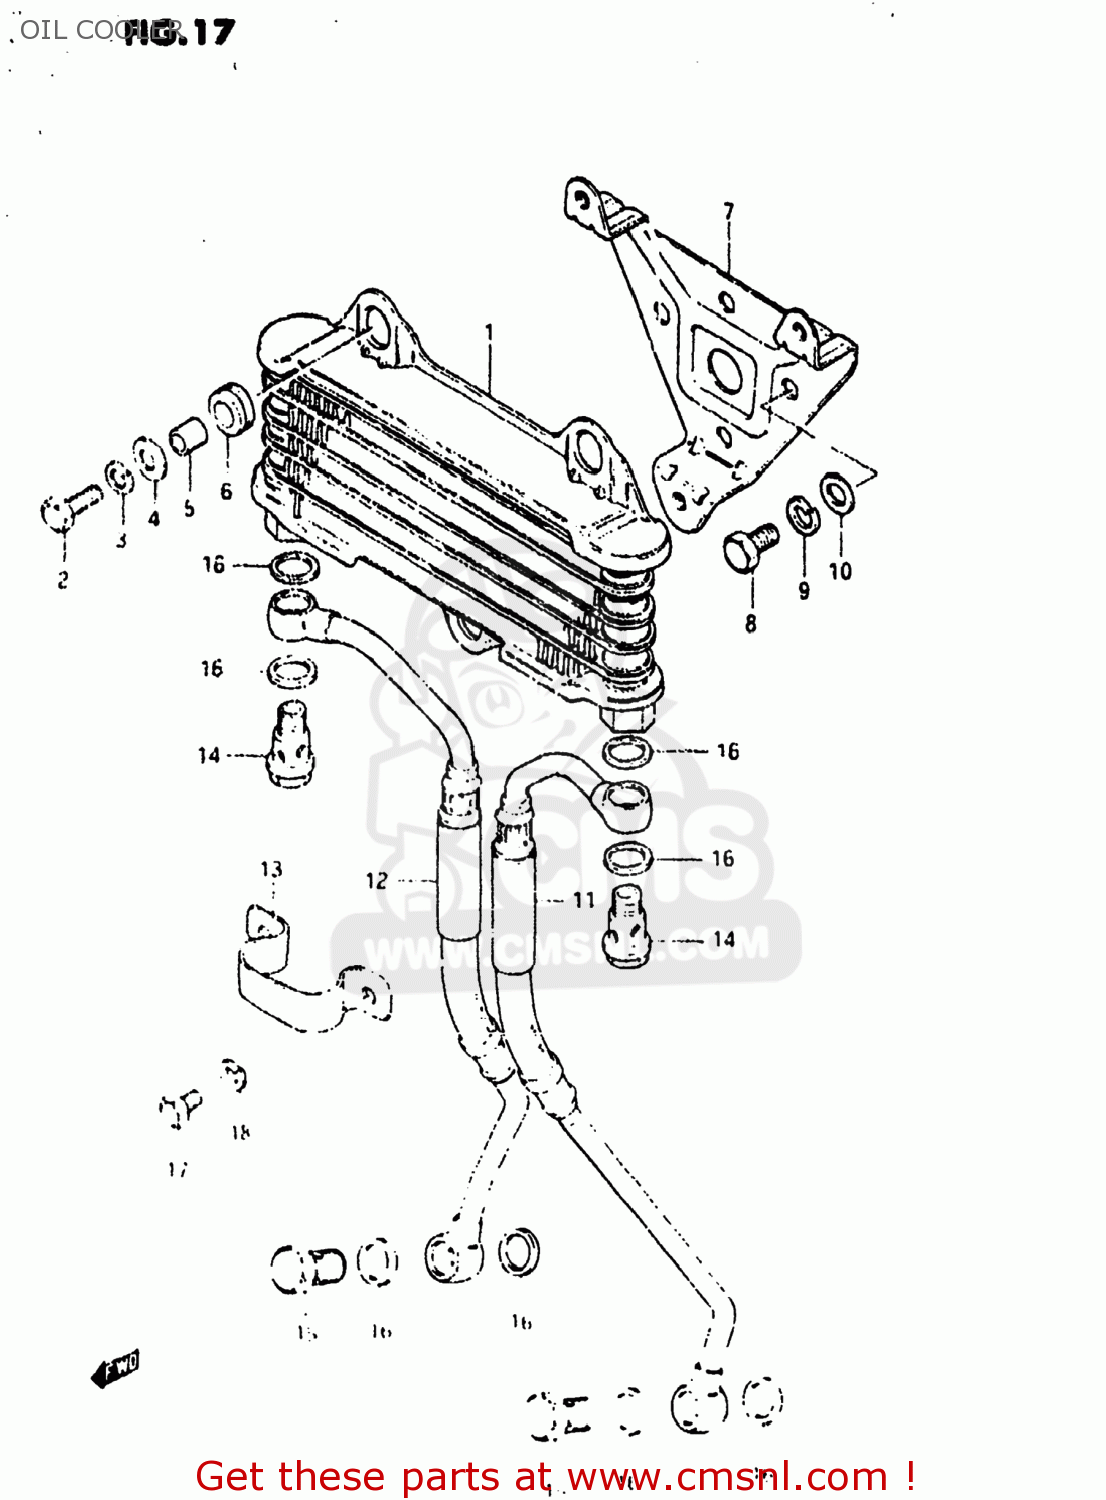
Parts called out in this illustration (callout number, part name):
1	COOLER ASSEMBLY,ENGINE OIL
2	BOLT
3	WASHER,LOCK
4	WASHER (6.5X18X1.6)
5	SPACER (6.8X10X10)
6	CUSHION
7	BRACKET,OIL COOLER
8	BOLT
9	WASHER,LOCK,8.
10	WASHER
11	HOSE,ENGINE OIL,LEFT
12	HOSE,ENGINE OIL,RIGHT
13	CLAMP,OIL HOSE
14	BOLT UNION
15	BOLT UNION
16	GASKET(14X20X1.5) (NAS)
17	BOLT
18	WASHER,LOCK
